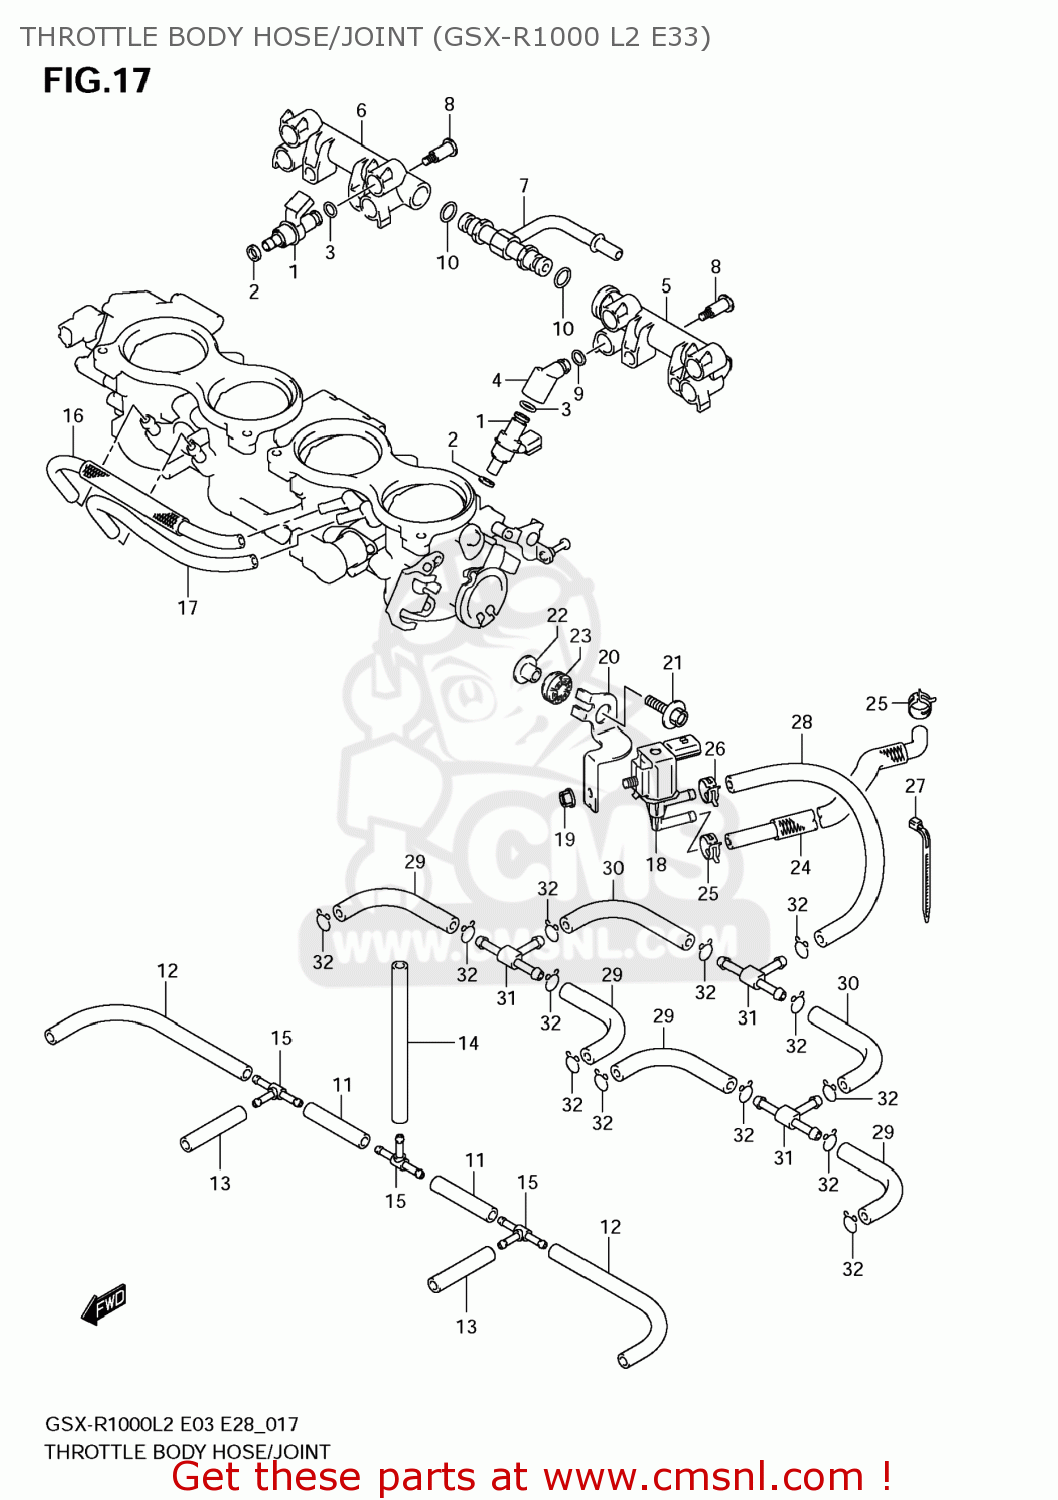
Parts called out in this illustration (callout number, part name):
1	INJECTOR ASSY
2	RING,SEAL
3	O RING
4	PIPE,FUEL
5	PIPE,FUEL
6	PIPE,FUEL
7	JOINT
8	SCREW
9	O RING
10	O RING
11	HOSE
12	HOSE
13	HOSE
14	HOSE
15	JOINT
16	TUBE
17	TUBE
18	VALVE,CANISTER PURGE
19	NUT
20	BRACKET,SOLENOID VALVE
21	BOLT(6X30)
22	SPACER(6.5X10X11.6)
23	CUSHION
24	HOSE,PURGE VALVE
25	CLIP
26	CLIP
27	CLAMP(L:125)
28	HOSE
29	HOSE
30	HOSE
31	JOINT
32	CLIP
